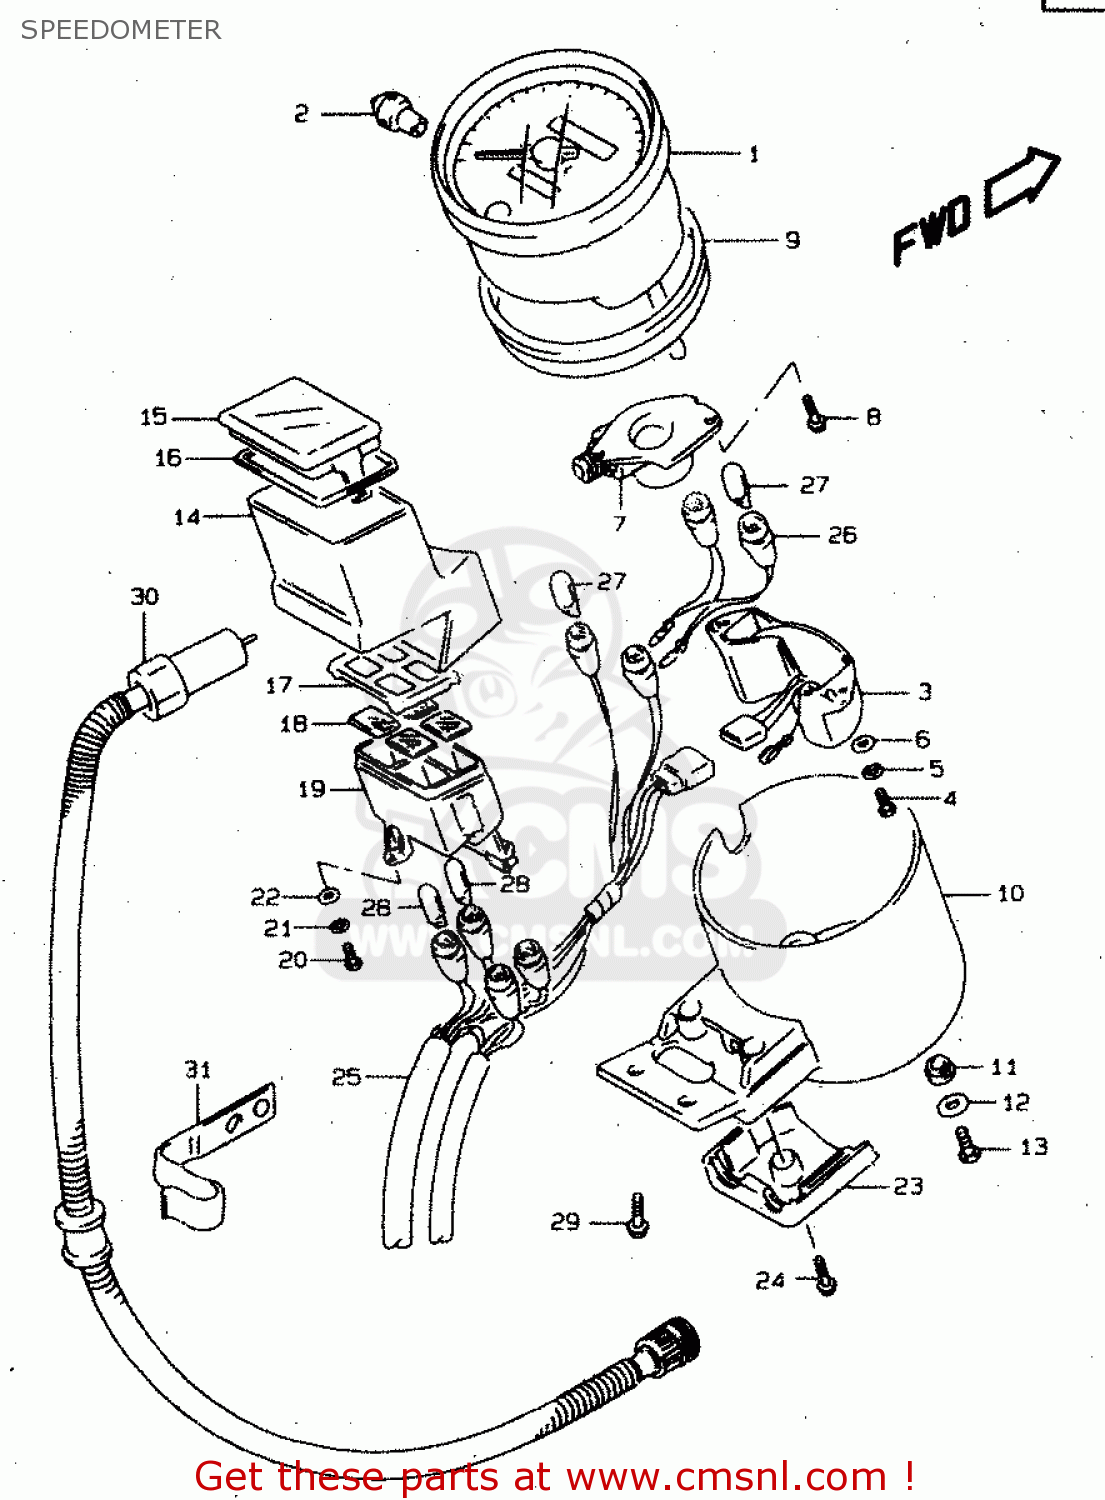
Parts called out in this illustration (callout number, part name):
1	SPEEDOMETER(KILO)
2	KNOB,TRIP
3	UNIT,WATER TEMP
4	SCREW
5	WASHER,LOCK
6	WASHER
7	BOX,GEAR
8	SCREW
9	CUSHION
10	COVER,METER
11	CUSHION,METER
12	WASHER
13	SCREW
14	BOX,PILOT
15	LENS,PILOT BOX
16	CUSHION
17	PLATE,PILOT LENS
18	LENS SET,PILOT LAMP
19	CASE,PILOT LAMP
20	SCREW
21	WASHER,LOCK
22	WASHER
23	COVER,PILOT BOX
24	SCREW
25	SOCKET,METER NO.1
26	SOCKET
27	BULB(12V3W,T6.5)
28	BULB(12V1.7W,T6.5)
29	SCREW
30	CABLE ASSY,SPEEDOMETER
31	GUIDE,SPEEDOMETER CABLE
